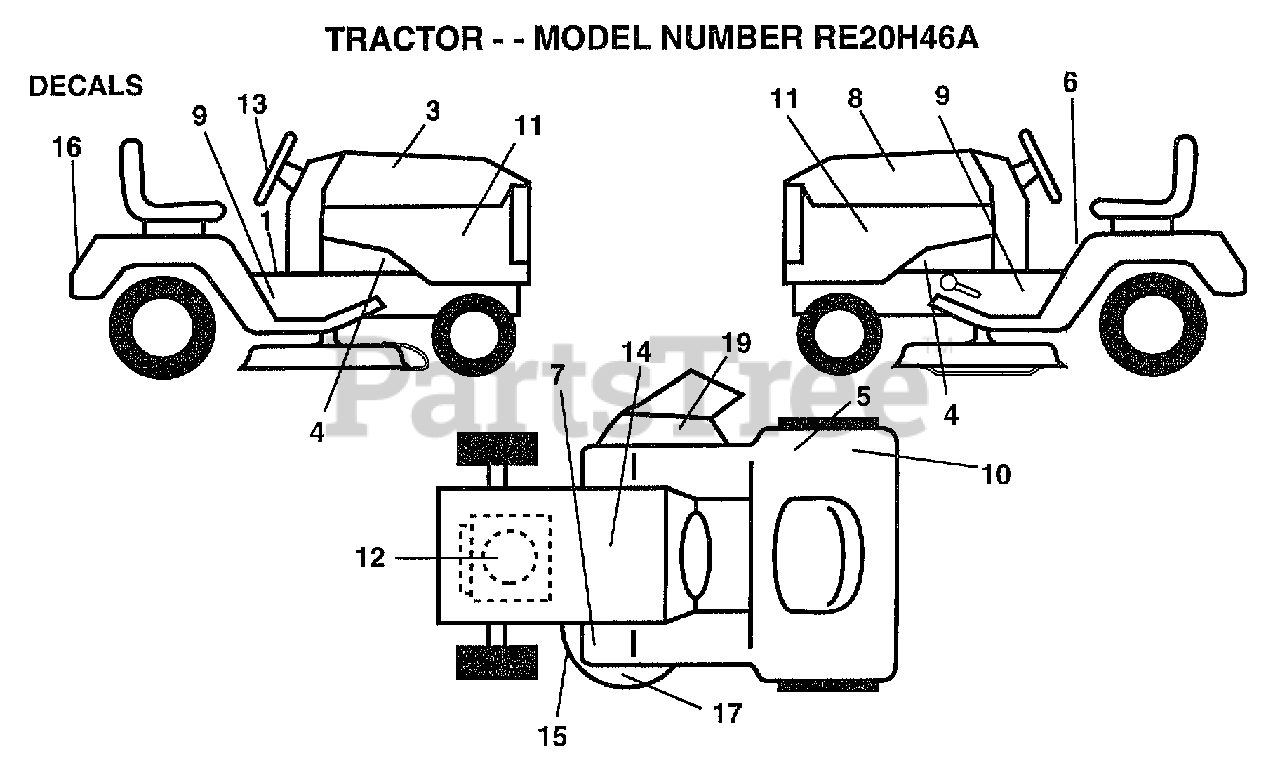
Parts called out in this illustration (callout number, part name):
1	DECAL BRAK PARK
3	DECAL.HD.RH.RALLY
4	"DECAL CHASSIS,HOT"
5	DECAL.EURO.ST.CE.
6	DECAL.READ.O.MANU
7	DECAL-BRAKE/CLUTC
8	DECAL.HD.LH.RALLY
9	"DECAL CHASSIS,46"""
12	DECAL .B&S.20HP
14	DECAL.BATRY.3-3908
16	FENDER DECAL
19	DECAL.DANGER.CUTF
